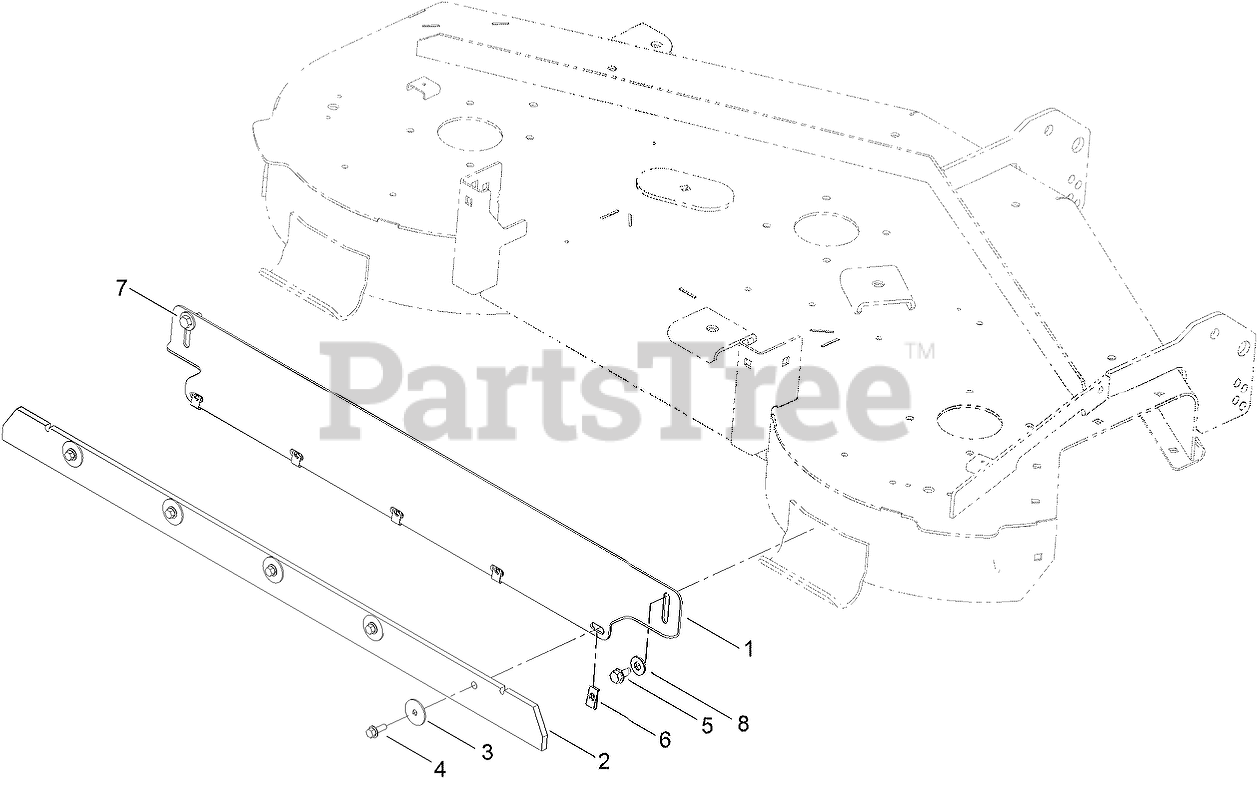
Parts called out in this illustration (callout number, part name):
1	BRACKET-STRIPING, 50IN
3	WASHER-FLAT
4	SCREW-HHF
5	SCREW-HWHTF
6	NUT-SPEED
7	SCREW-HWH, THD ROLL
8	WASHER-FLAT
